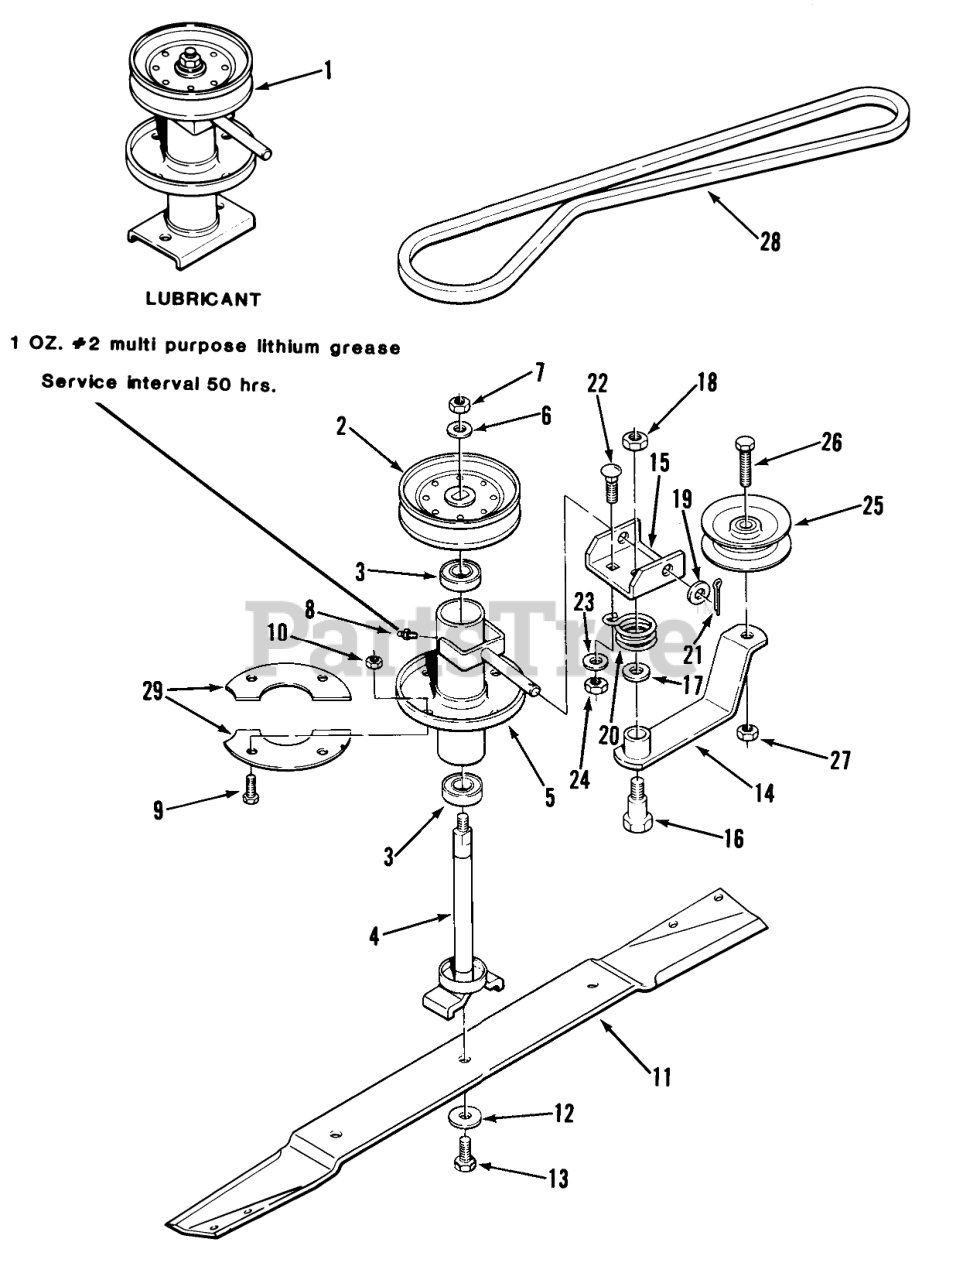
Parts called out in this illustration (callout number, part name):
1	Spindle Assy Complete
2	PULLEY SPINDLE
3	BEARING-BALL
4	Shaft And Blade Saddle Assy
5	Spindle Housing Assy
6	Washer
7	Top Lock Nut 3/8-24
8	Zerk
9	Bolt
10	Nut
11	Mower Blade
12	WASHER
13	Eslok Bolt 3/8-24 x 1
14	ASSY LEVER R
15	CHANNEL PIVOT R
16	BOLT-SHOULDER
17	WASHER
18	NUT-JAM(7/16-14)
19	Washer
20	SPRING-TORSION
21	Cotter Pin
22	Bolt
23	Washer
24	NUT
25	PULLEY IDLER
26	Bolt
27	NUT
28	Mower Drive Belt
29	SPACER SPINDLE
